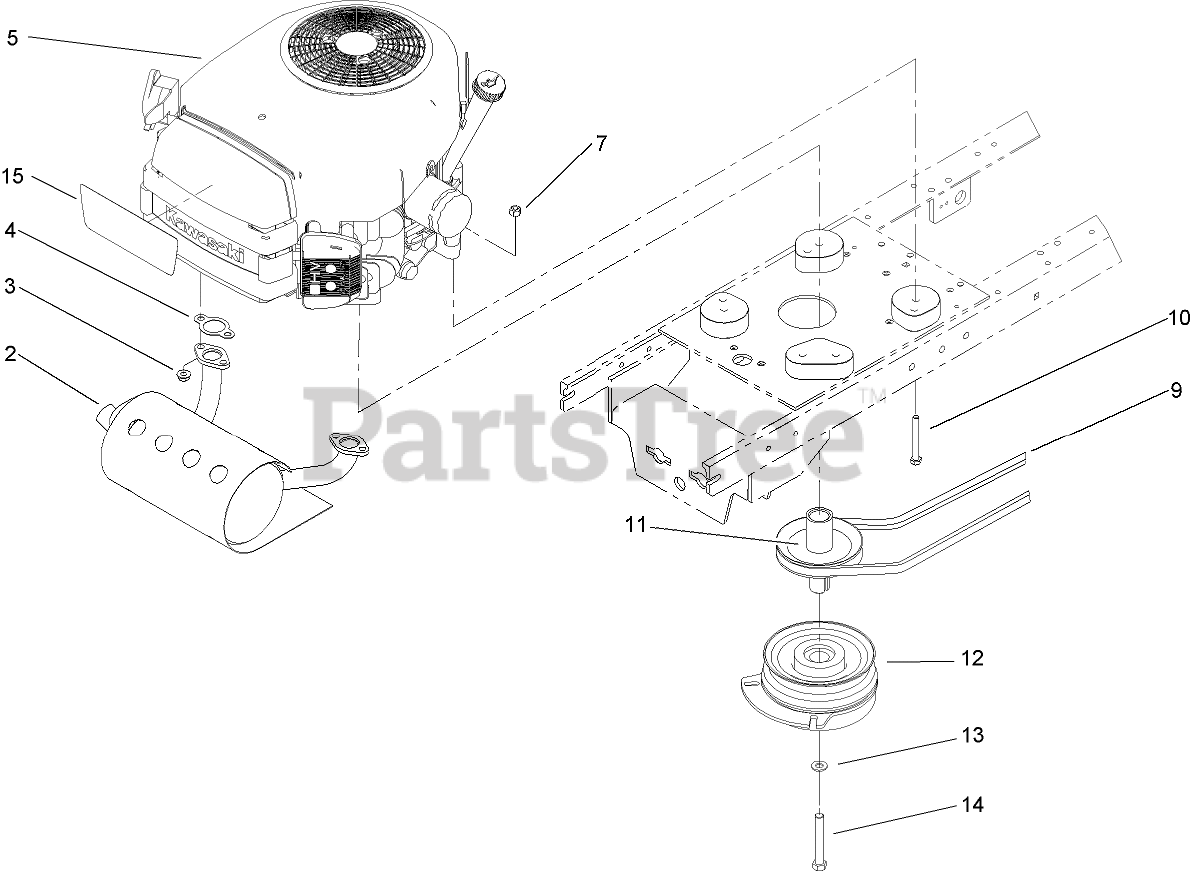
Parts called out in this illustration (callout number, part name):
2	MUFFLER
3	NUT-HF
4	GASKET-EXHAUST
7	NUT-LOCK, NI
9	V-BELT, TRACTION
10	SCREW-HH
11	Pulley-Engine
12	CLUTCH
13	WASHER-FLAT
14	SCREW-HH
